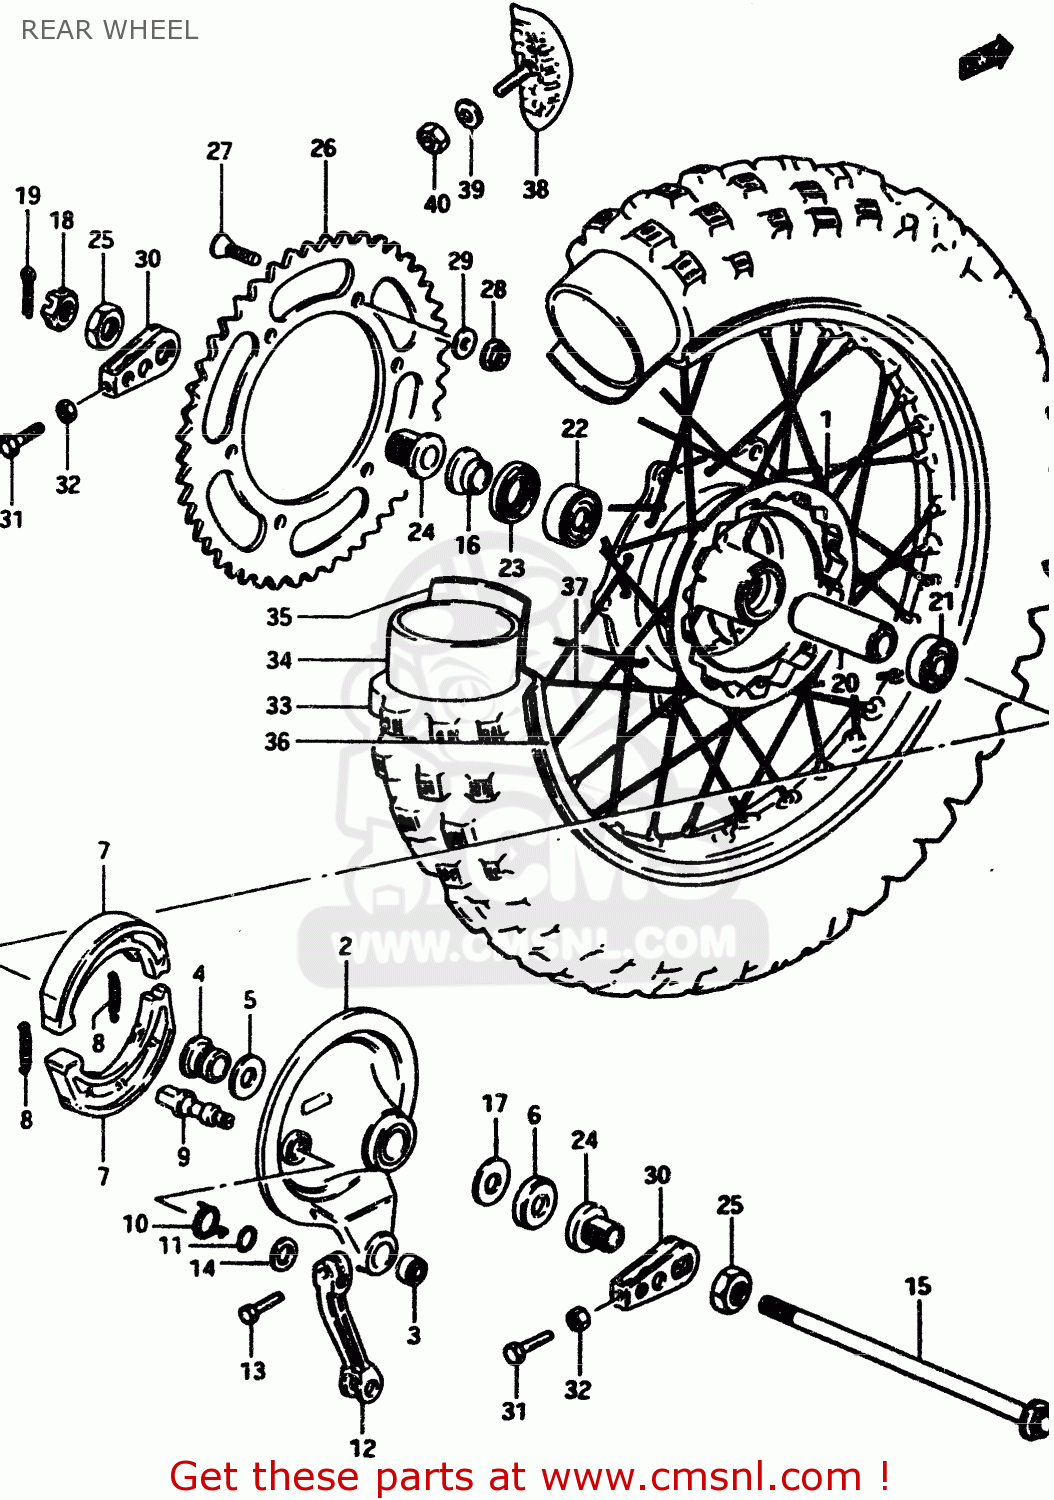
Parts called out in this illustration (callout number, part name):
1	DRUM,REAR HUB
2	PANEL SET,REAR
3	BEARING
4	SPACER,REAR HUB PANEL
5	SEAL,OIL(24X31X5)
6	CVR,RR BRAKE AHR PNL DUST SEAL
7	SHOE,BRAKE
8	SPRING,BRAKE SHOE
9	CAM,FR BRAKE
10	SPRING
11	O RING(D:2.5,ID:11.4)
12	LEVER,REAR BRAKE CAM
13	BOLT
14	WASHER(12.5X20X1)
15	AXLE,REAR
16	SPACER,REAR AXLE,LEFT
17	WASHER
18	NUT
19	PIN,COTTER
20	SPACER,REAR HUB BEARING
21	BEARING
22	BALL BEARING 17X47X22
23	OIL SEAL (25X47X7.5)
24	SPACER,CHAIN ADJUSTER
25	NUT
26	SPROCKET,REAR
27	SCREW(8X40)
28	NUT
29	WASHER
30	ADJUSTER,CHAIN
31	BOLT
32	NUT
33	TIRE 140/80-18
34	TUBE ASSEMBLY,WHEEL,INNER
35	PROTECTOR,INNER TUBE
36	RIM, WHEEL (250X18)
37	SPOKE SET,REAR WHEEL
38	STOPPER,BEAD
39	WASHER
40	NUT
